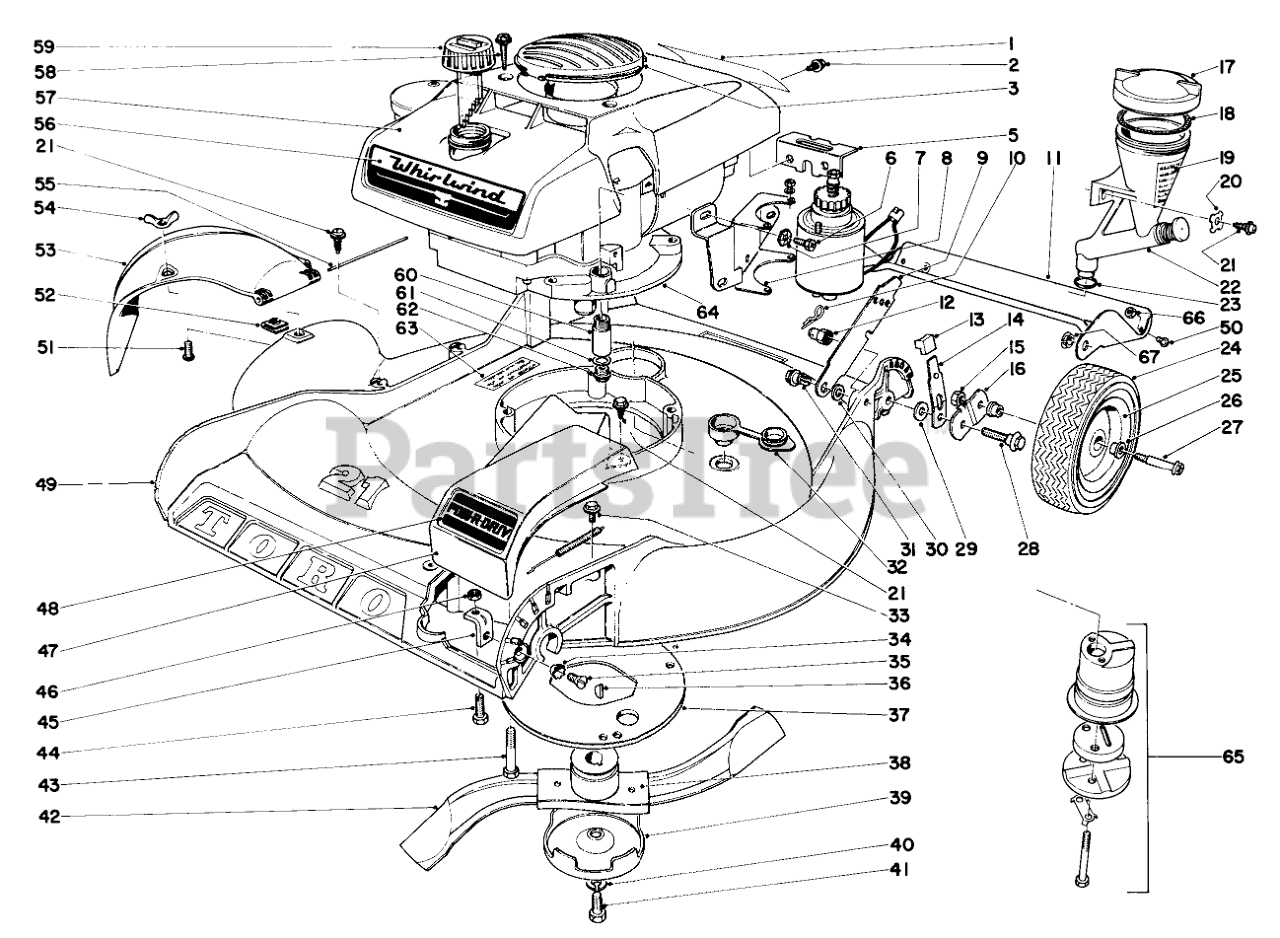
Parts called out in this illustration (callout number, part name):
1	Decal
2	Screw
3	Insert Shroud
5	Bracket
6	SCREW-HH
7	WASHER-FLAT
8	Bracket
9	Latch
10	PIN-COTTER, HAIR
11	Safety Shield-Rear
12	Nut
14	Spring Arm
15	Nut
16	Pivot Arm
17	Cap, Reservoir (Incl. Ref. 18)
18	"O" Ring
19	Decal, Reservoir
20	Washer
21	Screw
22	Reservoir, Oil
23	O-RING
24	8 TIRE
25	Wheel Assembly (Incl. Ref. 26)
26	FLANGE BUSHING
27	Wheel Bolt
28	Pivot Screw
29	WASHER-PIVOT
30	SPACER
31	SCREW-SHOULDER
32	Washer Plug
33	SCREW-HHF
34	Lockwasher
36	KEY-WOODRUFF
37	Grass Guard
38	BLADE RETAINER WA
39	Scalp Cup
40	WASHER-LOCK
41	SPECIAL SCREW
42	Blade
43	Screw
44	SCREW
45	ADJ BRACKET
46	NUT-JAM
47	Guard, Belt
48	Decal
49	Housing
50	Screw-Nylon
52	NUT-SPEED
53	Deflector
54	NUT-WING SPECL
55	HINGE PIN
56	Decal
57	Shroud
58	SCREW-HWH
59	Gas Cap
60	Extension Oil Drain
61	Gasket-Oil Drain
62	Plug Oil Drain
63	Decal
64	Engine
65	Muffler
66	NUT-JAM
67	Nyliner
